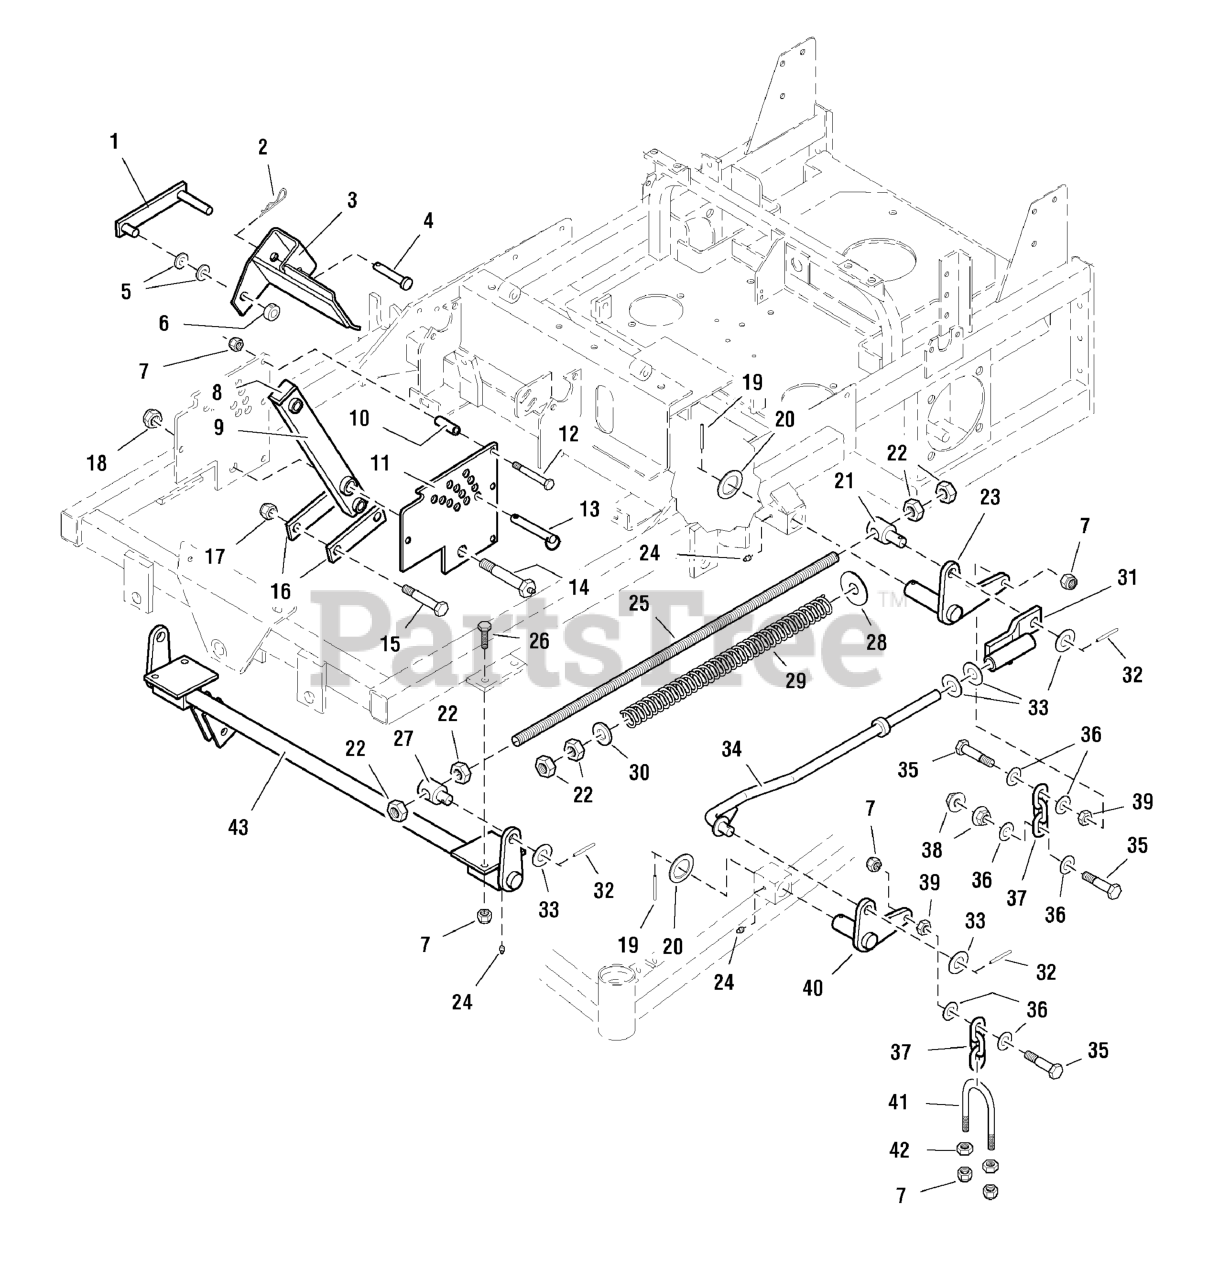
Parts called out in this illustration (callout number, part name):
1	DECK LIFT LOCK
2	HAIRPIN CLIP
3	WELD, DECK LIFT PEDAL
4	PIN, Clevis, 1/2 x 2-1/2
5	WASHER, 1/2 SAE
6	COLLAR, Split, 1/2
7	NUT, 3/8-16 HEX NYLON LOCK
9	ARM, Deck Lift Pivot
10	SPACER, .38 x .50 x 1.56
11	DECK HEIGHT PLATE
12	BOLT, 3/8-16 X 2-3/4" GD5 CZ
13	PIN, 1/2 x 3-1/2 w/ Lanyard
14	LIFT PIVOT BOLT
15	BOLT, 1/2-20 x 3
16	LINK, Deck Lift
17	NUT, Hex, Nylon Lock, 1/2-20
18	NUT, 5/8-11 Hex Jam Nylon Lock
19	PIN, Roll, 3/16 x 1-1/2
21	SPRING ROD PIVOT
22	NUT, 5/8-11 Hex
23	DECK LIFT PIVOT - LH
24	GREASE FITTING
25	SPRING ROD
26	BOLT, 3/8-16 X 1-1/4" GD5 CZ
27	SPRING ROD PIVOT
28	WASHER, 5/8" USS
29	SPRING, Deck Lift
30	SPACER, .63 x 1.06 x .23
31	DECK LIFT OFFSET LINK-LH
32	PIN, Spring, 3/16 x 1-1/4
33	WASHER, 5/8" SAE
34	DECK LIFT ROD-LH
35	BOLT, 3/8-16 X 1-3/4" GD5 CZ
36	WASHER, 3/8 SAE
37	CHAIN, 3 LINKS
38	NUT, 3/8-16 Hex Serrated Flange
39	NUT, 3/8-16 HEX JAM
40	DECK LIFT PIVOT-LH
42	NUT, 3/8-16 Hex
43	DECK LIFT SHAFT & MOUNT ASSEMBLY
